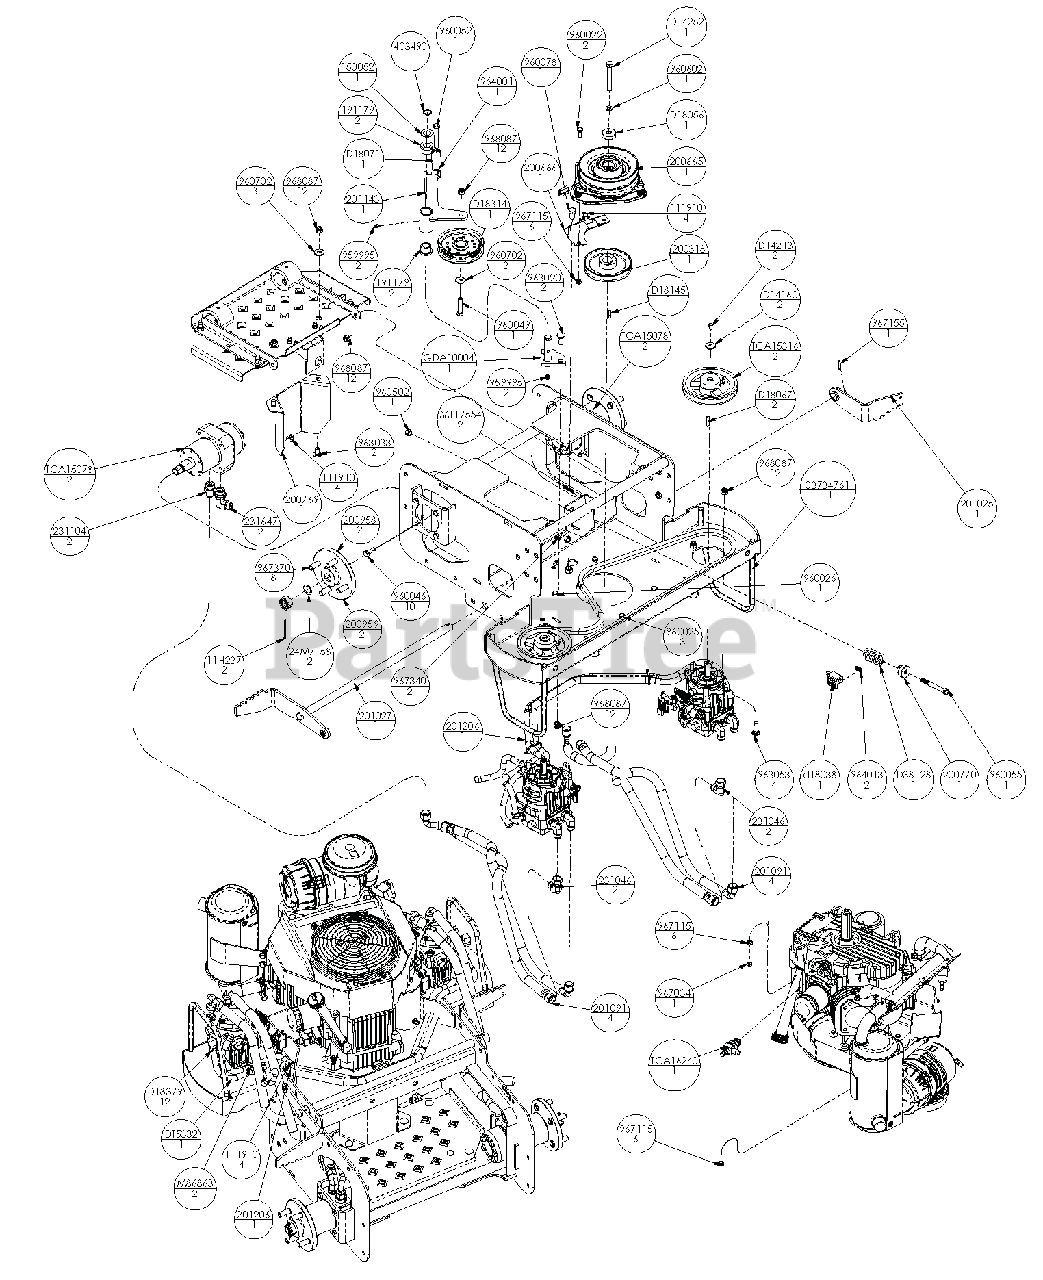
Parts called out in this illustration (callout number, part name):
1	HOSE, 3/8 SAE30R7 FUEL & OIL
2	WASHER, .250 WIDE HEAVY FLAT Y
3	BOLT, M6X1.00X10 HEX 8.8 Y
4	BOLT, 7/16-20X3.00 HEX 5 Y
5	SWITCH (N.0.)
6	SPACER, .468 X 1.38 X .375 Y
7	SHAFT KEY
8	SPRING, EXT .900X.135X4.50 Y
9	PULLEY, V-BELT4.00X.379 W/BRG
10	CLAMP, HOSE - 1/2" PINCH
11	SPRING, COM 1.22X.162X2.50 Y
12	WLDT, PIVOT IDLER MOUNT
13	LABEL, WARNING (HOT SURFACES)
14	FTG, TUN 3/8 HOSE
15	MOTOR, WHEEL HGM-12P-7172
16	ASSY, PUMP PULLEY W/SET SCREW
17	FITTING, OIL DRAIN #
18	PIN,.125X2.00 ZN COTTER 1010 #
19	CABLE TIE, .15 X 8.50
20	WSHR-FL-STL .750X1.250X.048 YZ
21	BRG, FLG .750X1.00X.750 BRNZ
22	PULLEY, V-BELT 4.78PD X 1.000
23	CLUTCH ASSY, OGURA# GT1A-HU02
24	PLATE, CLUTCH DOG
25	COVER, OPC
26	WASHER, SPRING Y
27	WHEEL HUB, MACHINED
28	ASSY, REAR WHEEL HUB
29	BELT, HA 68.2 EL AMD OHR
30	WLDT, RH BRAKE ARM
31	WLDT, LH BRAKE
32	HOSE, HYD 1/2 X 26 1/2 EZFLEX
33	WLDT, 34 FRAME PAINTED EVERIDE
34	WLDT, IDLER PIVOT
35	ABRASION SLEEVE
36	FTG, ADP MJIC-FSWJIC 6500-08-08
37	FTG, ADP 3/4-16MJICX7/8-14MOR
38	FTG, ADP JIC-ORB 2062-10-8S
39	SHIM, .020X.787X1.102
40	SNAP RING, .750 X .042 EXT
41	FTG, 1/4-28 STRGT GREASE ZERK
42	BOLT, 5/16-18X.750 HEX 5 Y
43	BOLT, 5/16-18X1.50 HEX 5 Y
44	BOLT, 5/16-18X1.75 HEX 5 Y
45	BOLT, 3/8-16X1.00 HEX 5 Y
46	BOLT, 3/8-16X1.75 HEX 5 Y
47	BOLT, 3/8-16X2.50 HEX 5 Y
48	BOLT, 3/8-16X3.25 HEX 5 Y
49	BOLT, 7/16-14X.750 HEX 5 Y
50	NUT, 3/8-16 STD HEX GR5 Y
51	WASHER, .375 MED SPRG LOCK Y
52	WASHER, .375 REG FLAT Y
53	BOLT, 3/8-16X1.00 CRG 5 Y
54	BOLT, 3/8-16X.750 CRG 5 LN Y
55	BOLT, 3/8-16X1.25 CRG 5 Y
56	NUT, 3/8-16 JAM GR5 Y
57	LOCKNUT, 10-24 NYLOC Y
58	NUT, 5/16-18 JAM GR5 Y
59	LOCKNUT, 5/16-18 NYLOC Y
60	PIN, ROL .156 X 1.00
61	SCREW, 10-24X.625 PAN PHL MACY
62	BOLT, 1/2-20X1.66 SPC 8 Y
63	LOCKNUT, 3/8-16 NYLOC Y
64	KEY, .250 X .250 X .995 TPR
